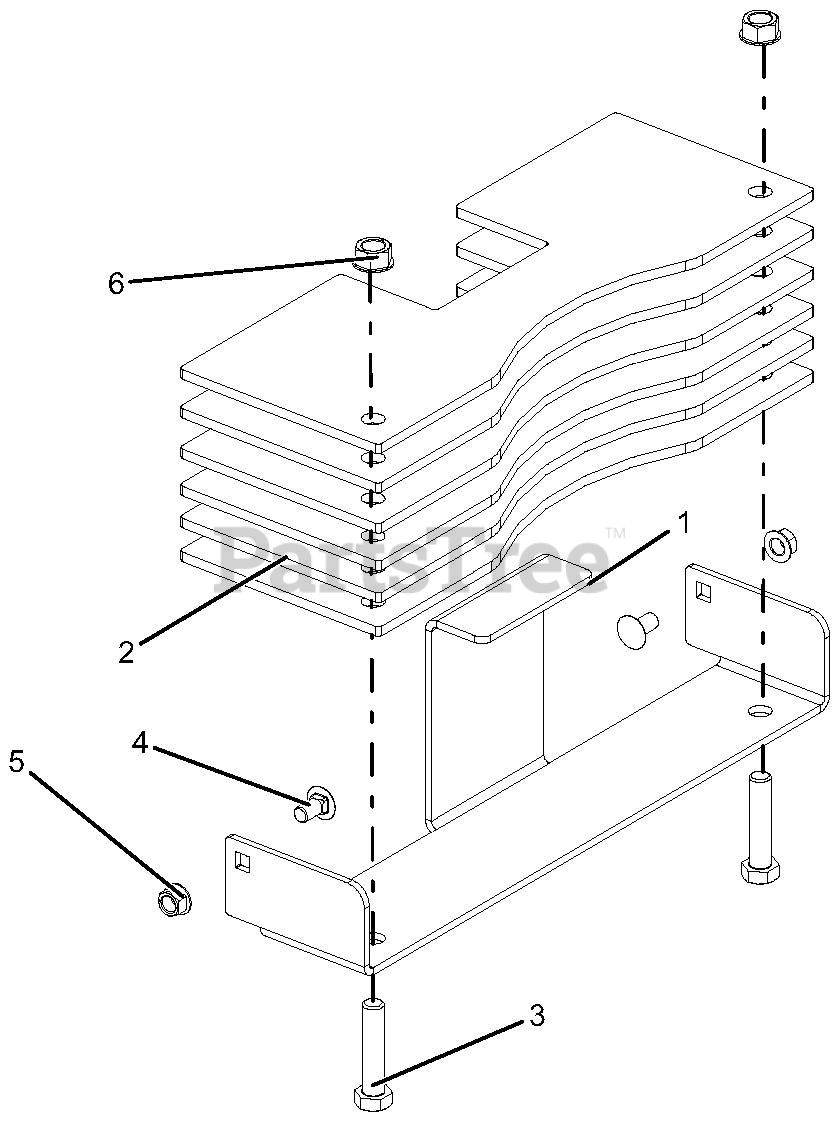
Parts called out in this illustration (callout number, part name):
1	BRACKET, WEIGHT -BAGGER
2	WEIGHT, BAGGER
3	@BLT-HEX .50-13X2.25 GR5 YWZC
4	@BLT-RDHDSQNK .38-16X.75 G5YZ
5	@NUT-LK-TOP-FLG .38-16 YWZC
6	@NUT-LK-TOP-FLG .50-13 YWZC
